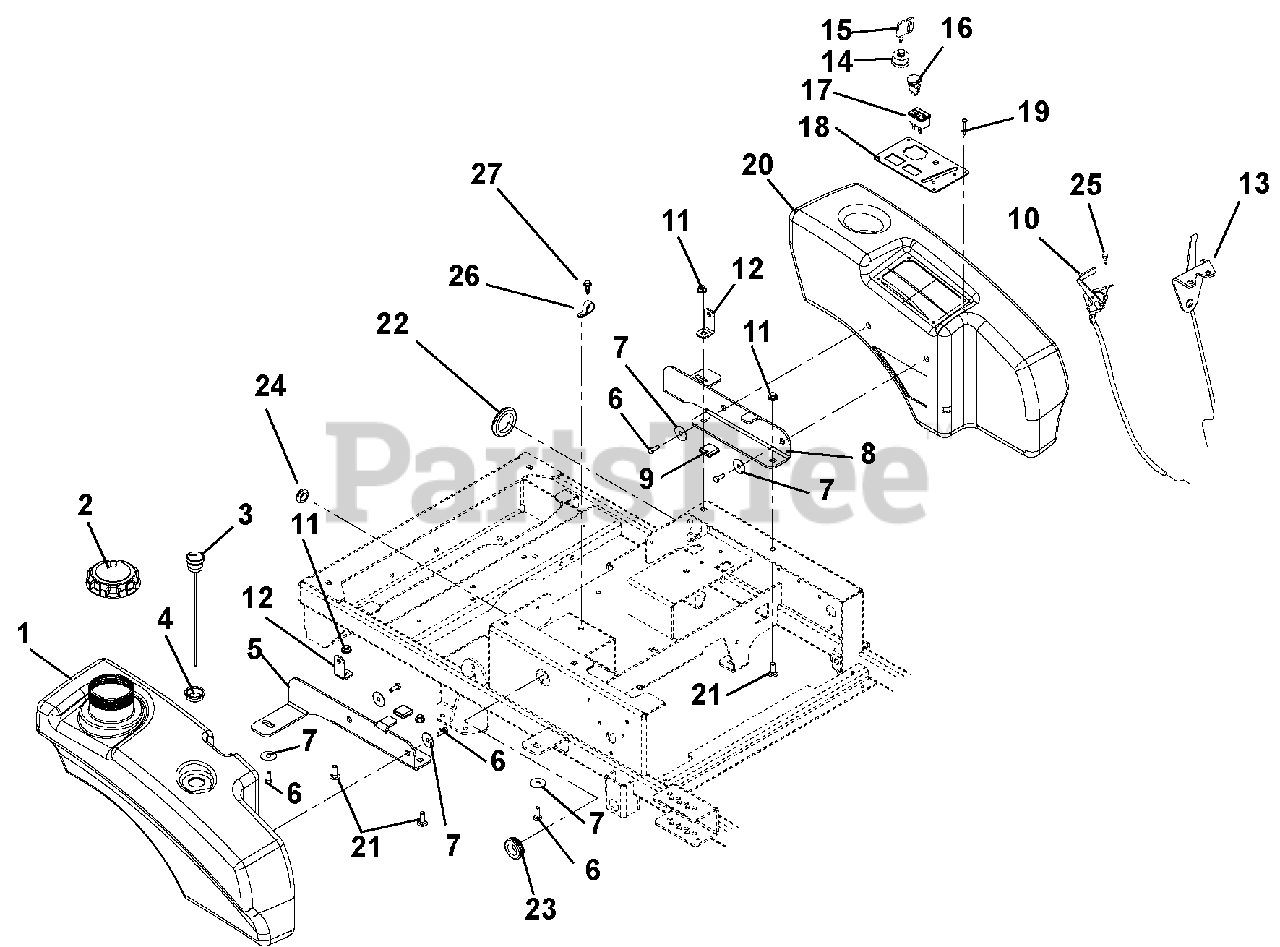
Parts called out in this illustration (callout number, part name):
1	TANK, XL
2	CAP, FUEL
3	GAUGE, REMOTE FUEL 10.0"
4	GROMMET, FUEL GAGE
5	BRKT, RH REAR TANK MOUNT
6	BLT-SERHFWH .312-18X.50 YWZC
7	WSHR-FL-STL .347X1.254X.048YWZ
8	BRKT, LH REAR TANK MOUNT
9	GRIP, RUBBER (1.0X1.0X.187)BLK
10	CABLE, THROTTLE - KAWI FR (XL)
10	FLATWASHER 1/4 ZP D STD 15918
11	@NUT-LK-NYL-FLG .38-16 YWZC
12	BRKT, HOOD PIVOT
13	CABLE, CHOKE - KAWI FR (XL)
13	CABLE, XL CHOKE
14	KEY SWITCH
15	KEY -W/CAP
16	SWITCH, CLUTCH
17	HOUR METER - DIGITAL
18	CONTROL PANEL
19	RIVET, PLASTIC .195 DIA.
20	FENDER, XL
21	@BLT-RDHDSQNK .38-16X1.00 G5YZ
22	GROMMET 1.70ID X 2.0OD
23	GROMMET 1.0ID X 1.38 OD
24	GROMMET,RUBBER 5/8 ID/1.13 OD
25	@SCR-TAP 10-24X.50 HWH TR YWZC
26	CLAMP, CUSHIONED STEEL .75
27	@SCR-TAP .38-16X.50 HWH TR YWZ
